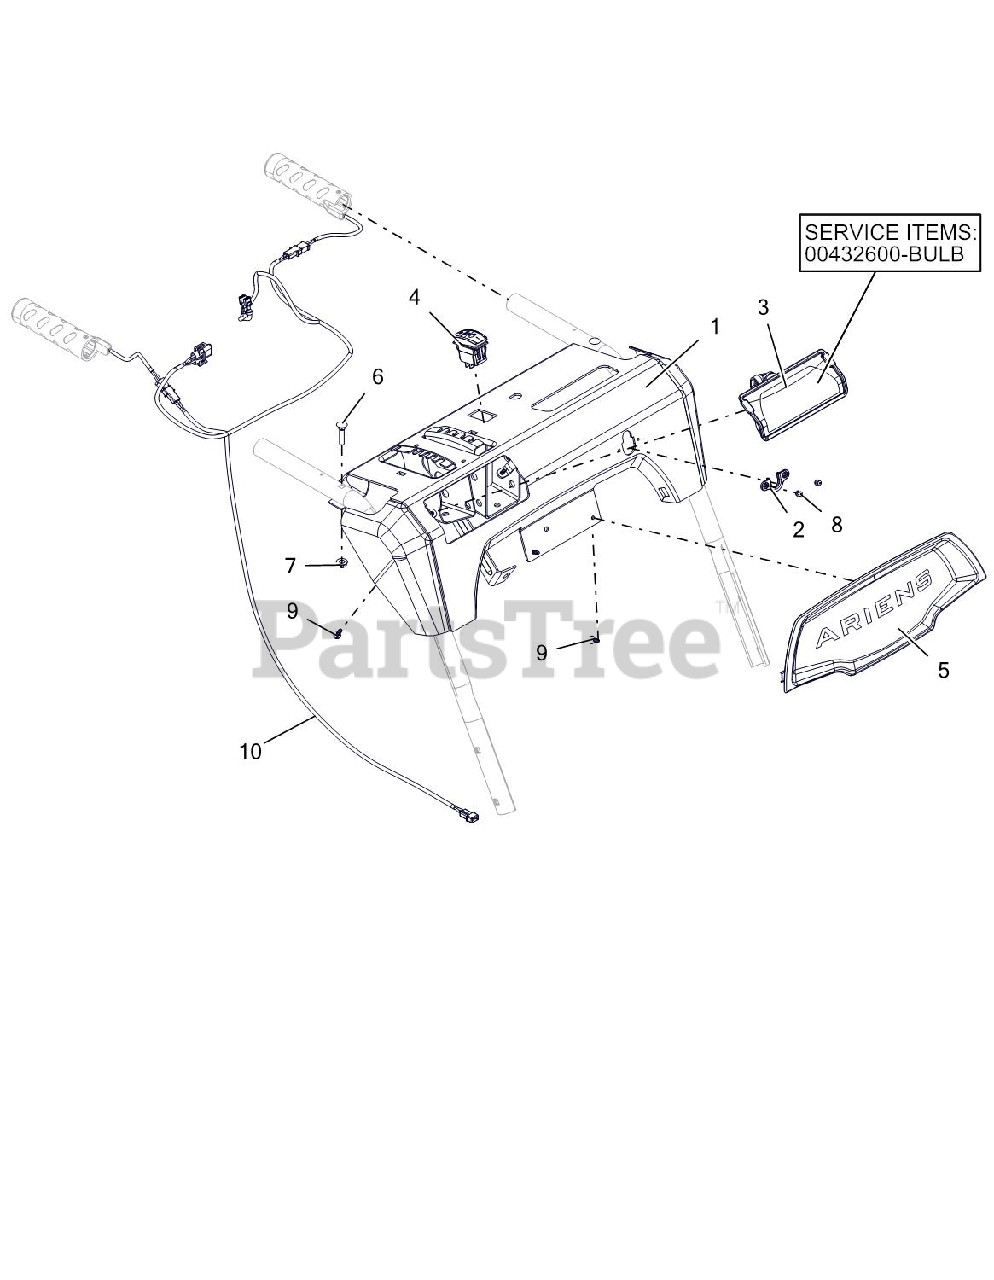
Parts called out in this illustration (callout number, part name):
1	CONTROL PANEL W/DECAL FRIC-QT
2	GROMMET, CABLE, QUICK TURN 2
3	BULB, LIGHT-HALOGEN 20W
3	HEADLIGHT ASY, HALO 20W 2SHOT
4	SWITCH,ROCKER SPST-ON/OFF
5	BEZEL, DASH - ARIENS LG DASH
6	BLT-RDHDXLSQNK.25-20X1.25 G5ZC
7	@NUT-LK-CTR-FLG .25-20 YWZC
8	RVT-POP #43 .125X.313 STL ZINC
9	SCR-TAP #10X.50 BOSS INDHXHD
10	HARNESS, LIGHT & WARMER
